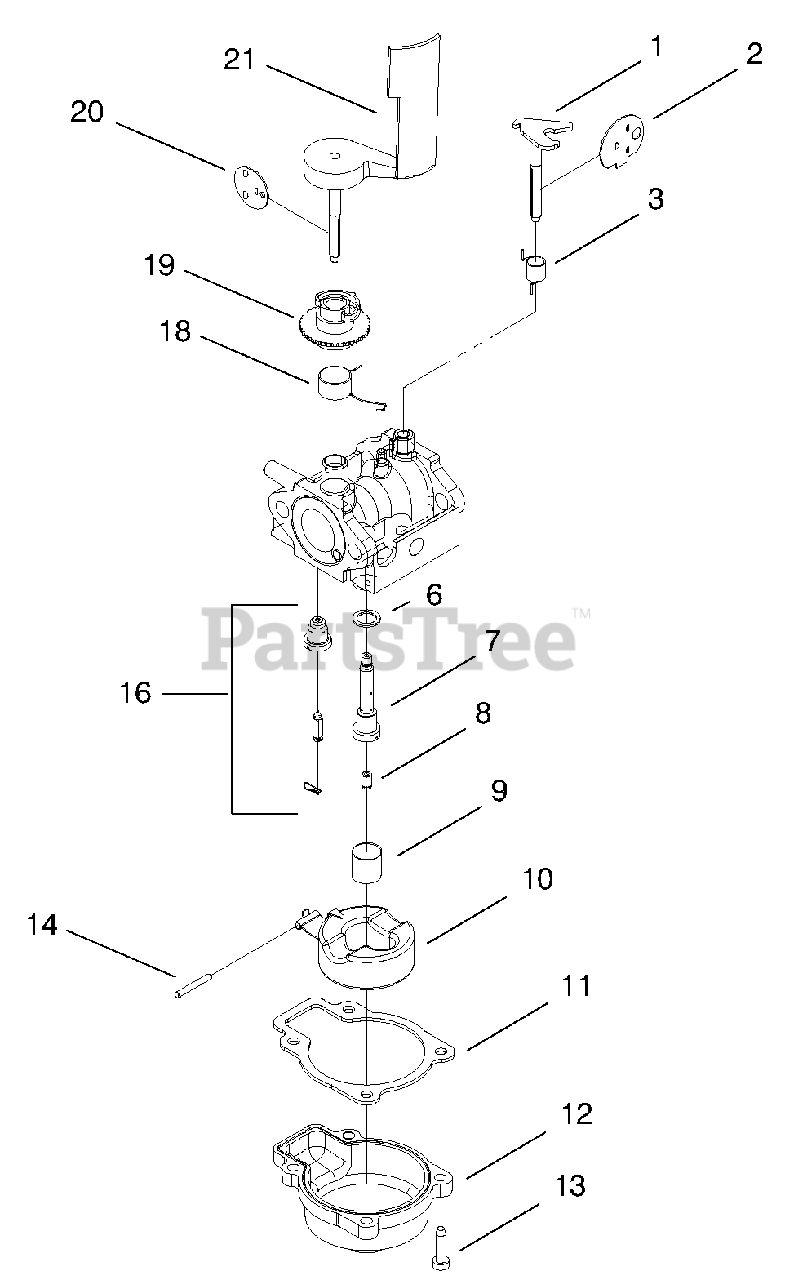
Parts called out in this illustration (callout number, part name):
1	Shaft-Choke
2	Disc-Choke
3	Spring-Choke
8	Jet-Main 77.5
9	Filter-Fuel
10	Float&arm Ay
12	Chamber-Float
13	Screw-HH
16	Val/Seat-Float
18	Spring-Gov.
19	Airvane-Collar
20	Disc-Throttle
21	Air Vane&shaft
